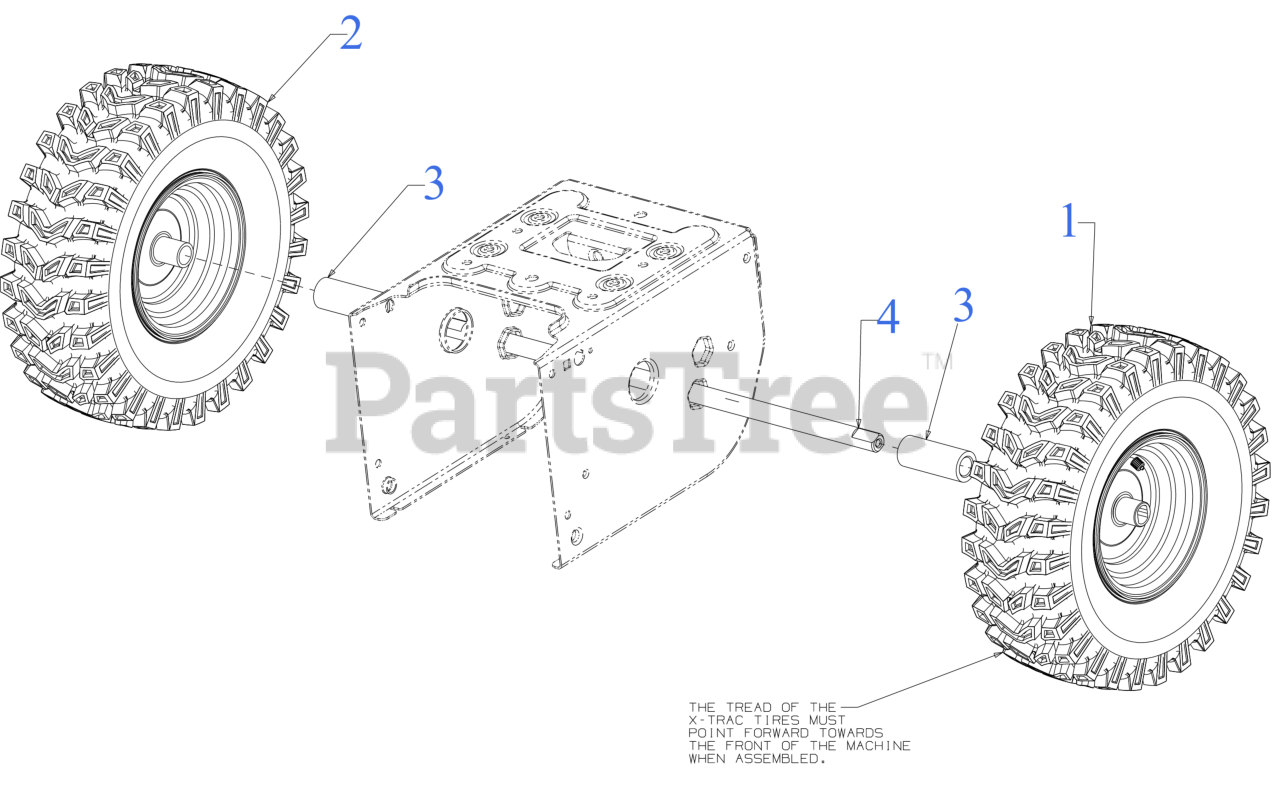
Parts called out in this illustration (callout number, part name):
1	WHL:COMPL:15X5.00-6 X-TRAC:LH
2	WHL:COMPL:15X5.00-6 X-TRAC:RH
3	WHEEL SPACER 1.25ODX.75X3.00
4	WHEEL AXLE SHAFT .75 x 22"
